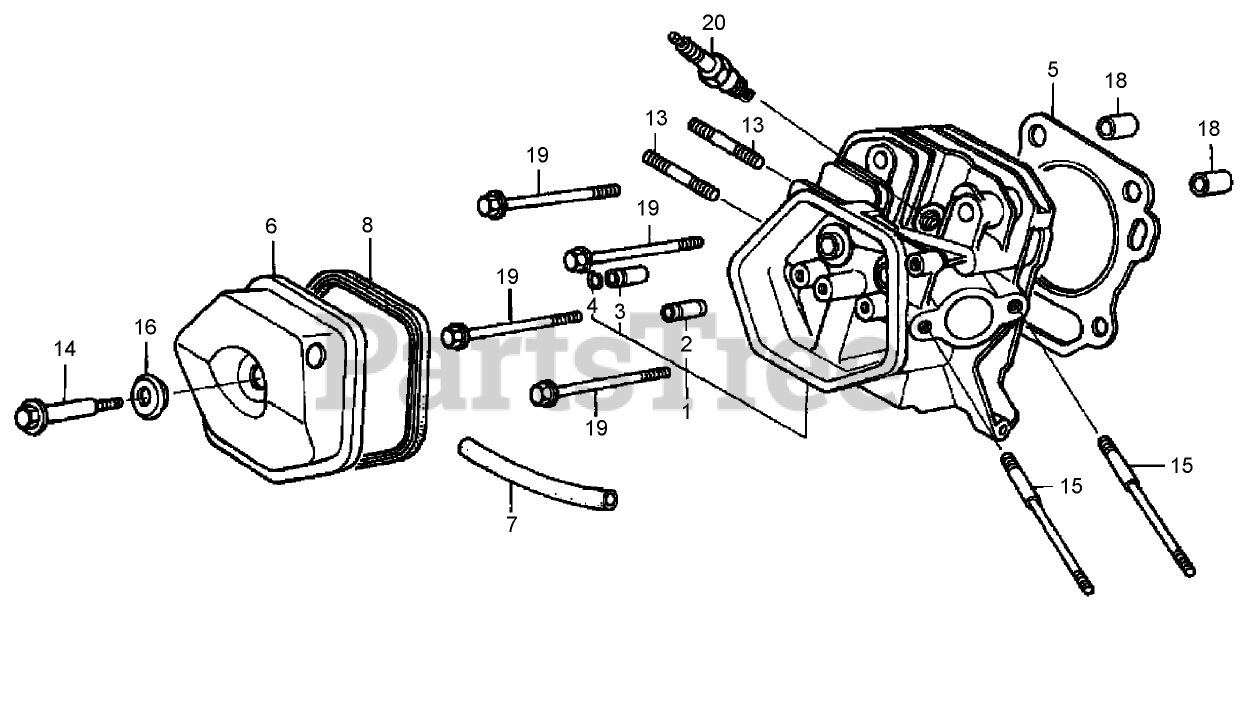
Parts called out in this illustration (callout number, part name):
1	CYLINDER HEAD
2	GUIDE-VALVE
3	GUIDE-VALVE, EXHAUST
4	CLIP-GUIDE, VALVE
5	GASKET-CYLINDER HEAD
6	COVER-HEAD
7	BULK HOSE-VACUUM
8	GASKET-CYLINDER HEAD COVER
13	BOLT 2-STUD
14	BOLT-HEAD COVER
15	BOLT-STUD
16	WASHER-HEAD COVER
18	PIN A-DOWEL
19	BOLT-FLANGE
20	SPARK PLUG (B P R 5E S) (N G K)
20	SPARK PLUG (W16E P R-U) (DENSO)
20	SPARK PLUG (B P R 6E S) (N G K)
